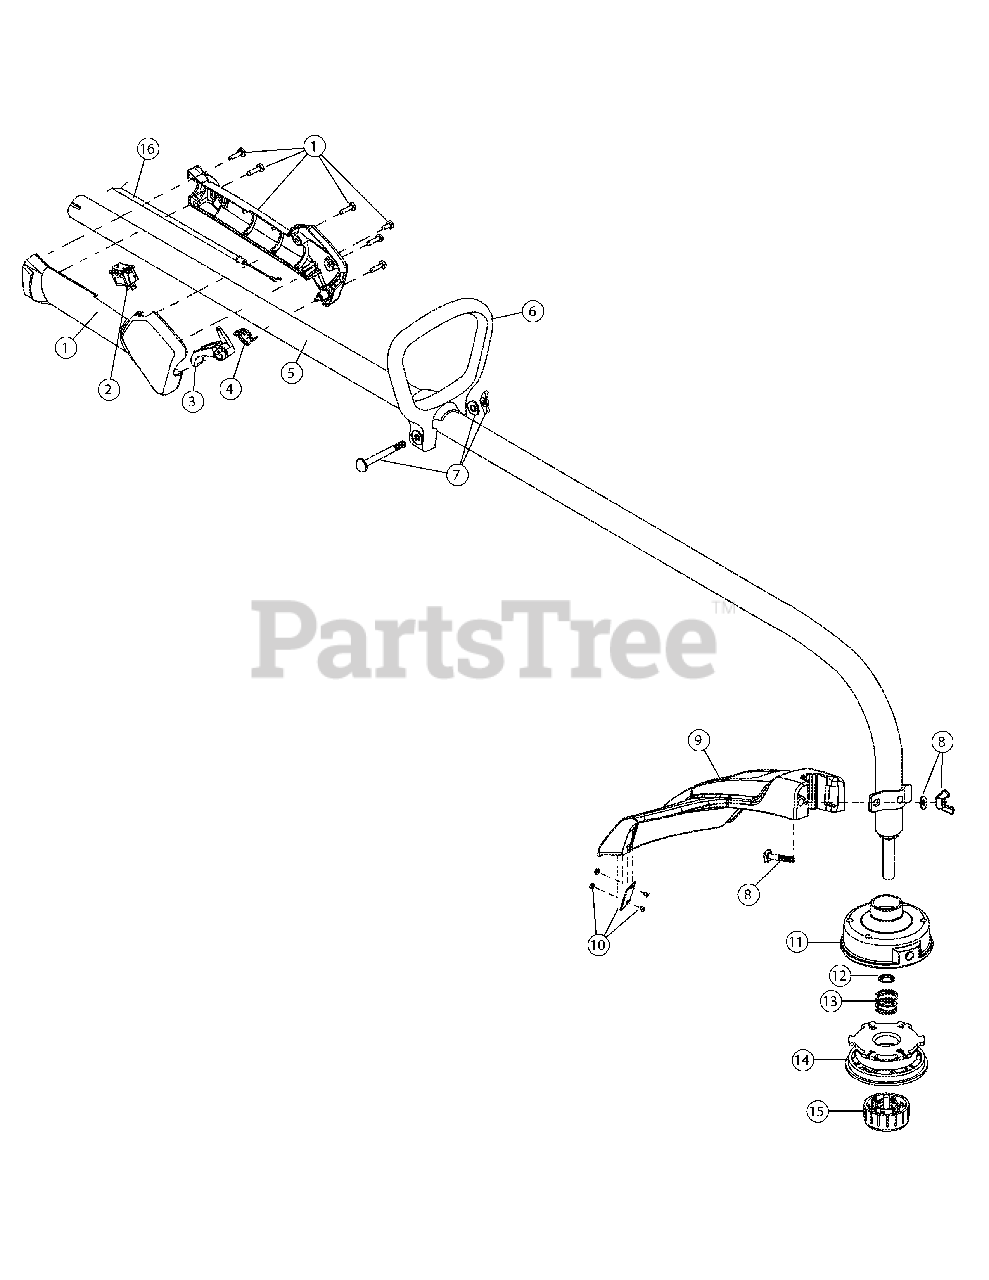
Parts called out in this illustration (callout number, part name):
1	Throttle Housing Assembly
3	Throttle Trigger
4	Throttle Trigger Spring
5	Drive Shaft Housing Assembly
6	D-Handle
7	Handle Hardware
8	Guard Mounting Hardware
9	Guard
10	Blade Assembly
11	Outer Spool Assembly
14	Inner Reel
15	Bump Head Knob Assembly
16	Throttle Cable
